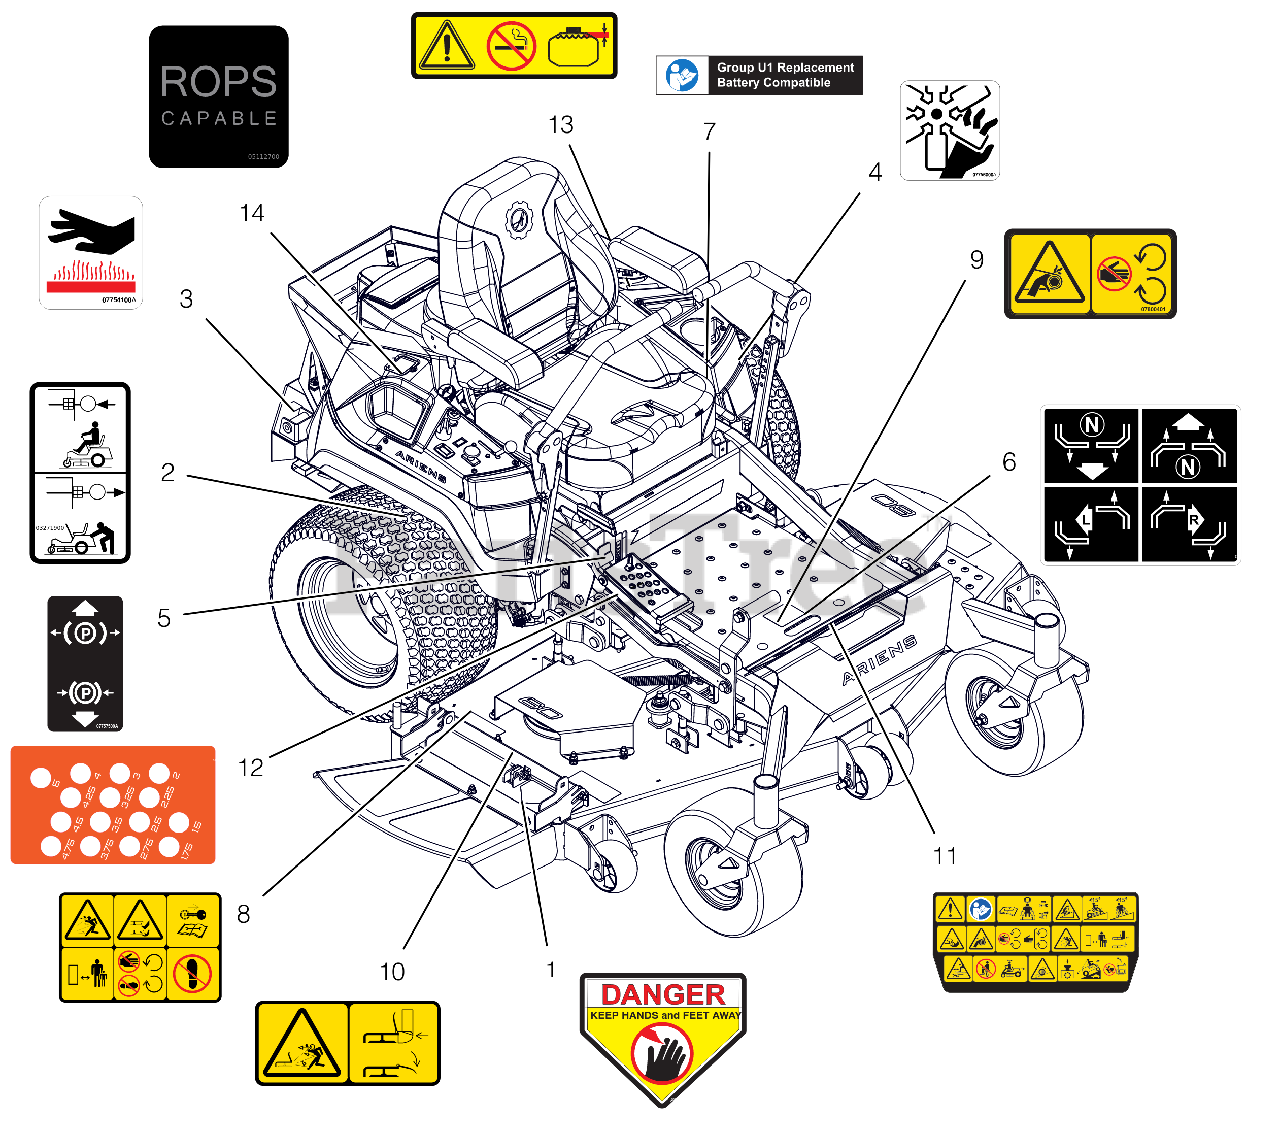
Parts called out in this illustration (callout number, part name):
1	DECAL, DANGER
2	DECAL, TRANSMISSION DISCONNECT
3	DECAL, HOT SURFACE
4	DECAL, DANGER FAN
5	DECAL, PARKING BRAKE LEVER
6	DECAL, INSTRUCTIONAL-STEERING
7	DECAL, U1 BATTERY REPLACEMENT
8	DECAL, SAFETY - MOWER DECK
9	DECAL, SAFETY - GUARDING
10	DECAL, SAFETY - DECK GUARDING
11	DECAL, MAIN SAFETY
12	DECAL, ARIENS HOC
13	DECAL, FUEL WARNING
14	DECAL, ROPS LOCATION
